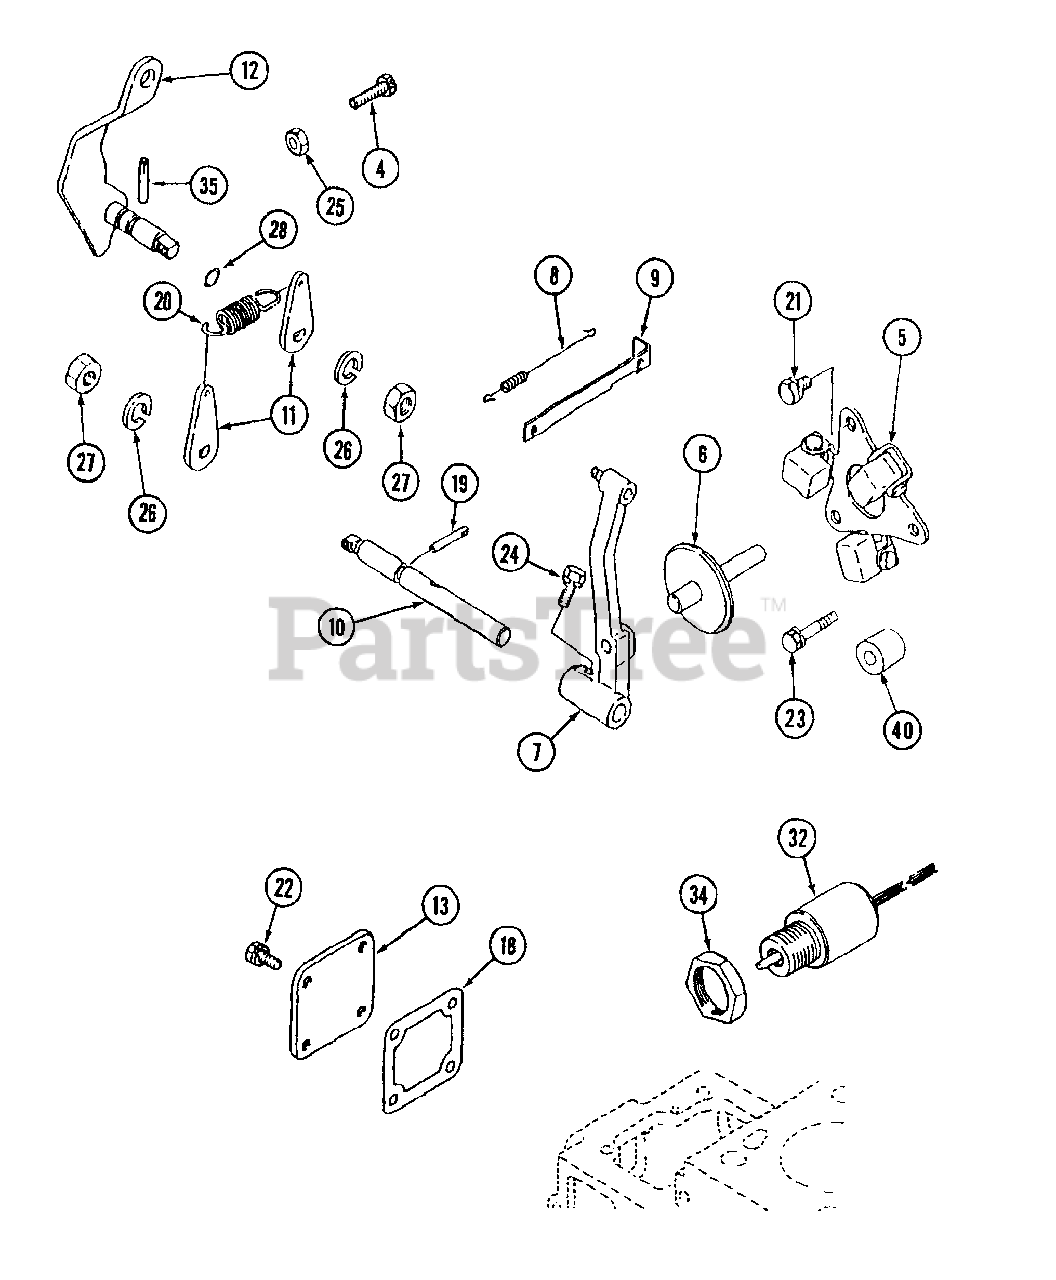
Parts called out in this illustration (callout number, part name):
4	Bolt, Idle Set
5	Weight Ass'y., Governor
6	Shaft Ass'y., Sliding
7	Lever Ass'y., Governor
8	Spring, Tie Rod
10	Shaft, Governor
11	Lever, Governor Spring
12	Lever, Speed Control
13	Cover Ass'y., Tie Rod
18	Gasket, Cover
19	Pin, Grooved
20	Spring, Governor
21	Bolt, w/Washer
22	Bolt, w/Washer
23	Bolt, w/Washer
24	Bolt, w/Washer
26	Washer, Spring
32	Solenoid & Nut Set
35	Pin, Grooved
